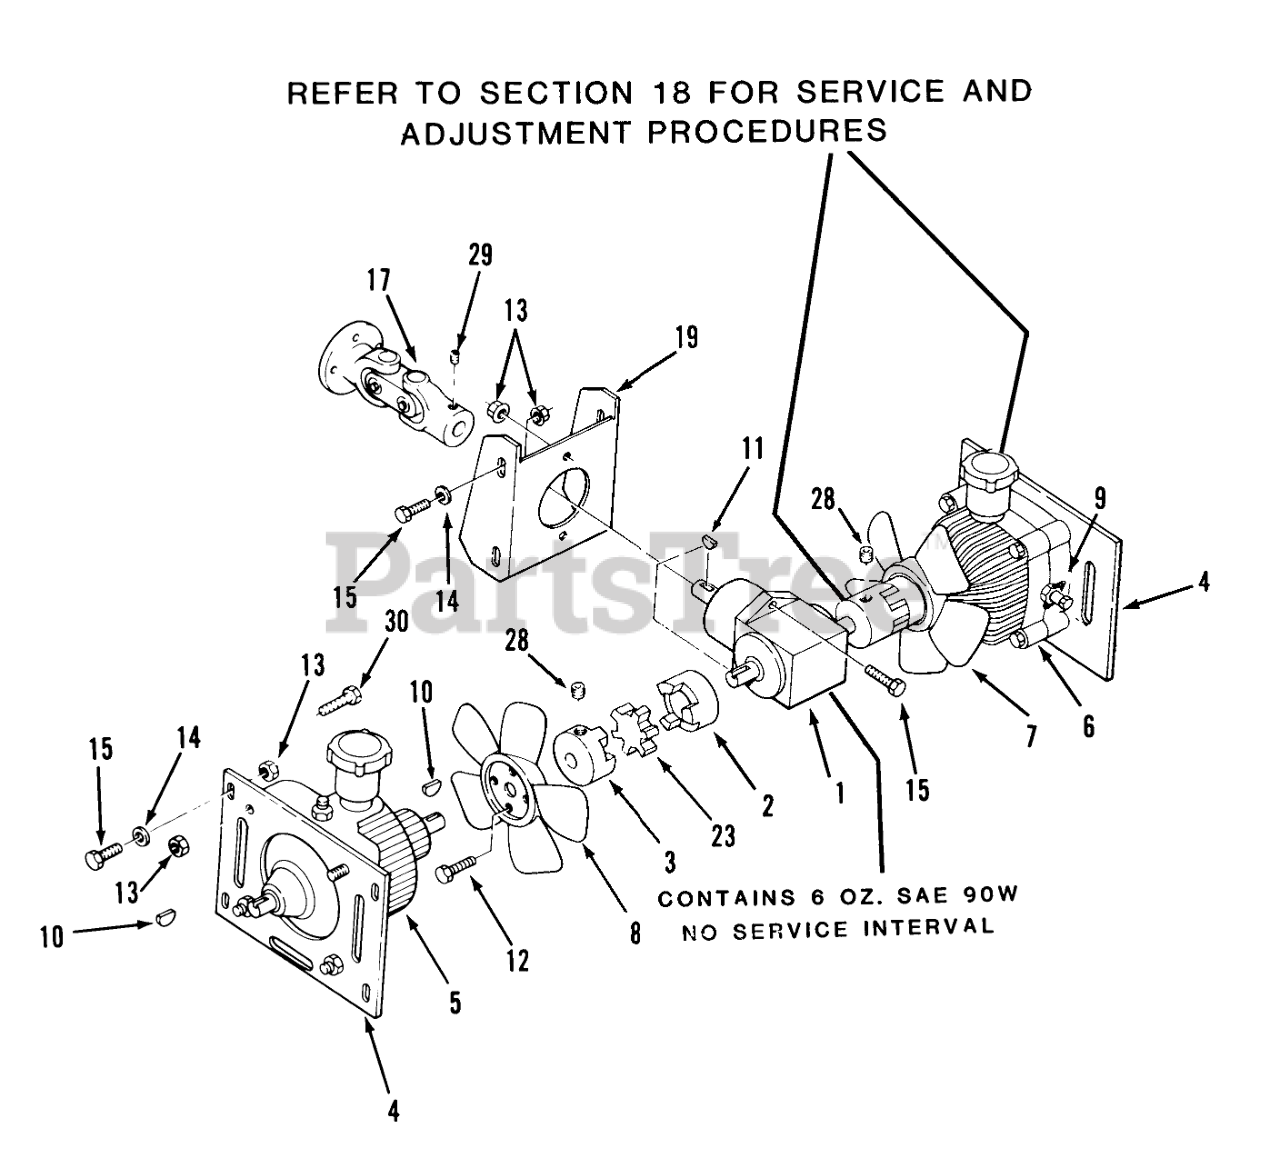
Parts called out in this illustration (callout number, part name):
1	"T" Gear Box (Peerless 1000)
2	LJ Coupler (.875 x 3/16 Keyway)
3	LJ Coupler (.670 X 1/8 Keyway)
4	Hydro Mounting Plate
5	Hydrostatic Transmission (counterclockwise rotation input shaft)
6	Hydrostatic Transmission (clockwise rotation input shaft)
7	Fan LH
8	Fan RH
9	Dump Valve Clip
10	KEY WOODR 1/8X1/2 DI
11	KEY-WOODRUFF
12	Self Tapping Screw #10-24 x 1/2
13	NUT
14	Washer
15	BOLT
17	ASSY-DOUBLE U-JOINT
19	GEAR BOX BRKT 20104K
23	Coupling Spider
28	Set Screw
29	Setscrew 3/8-16 x 1/2
30	Screw-Hex. Hd.
